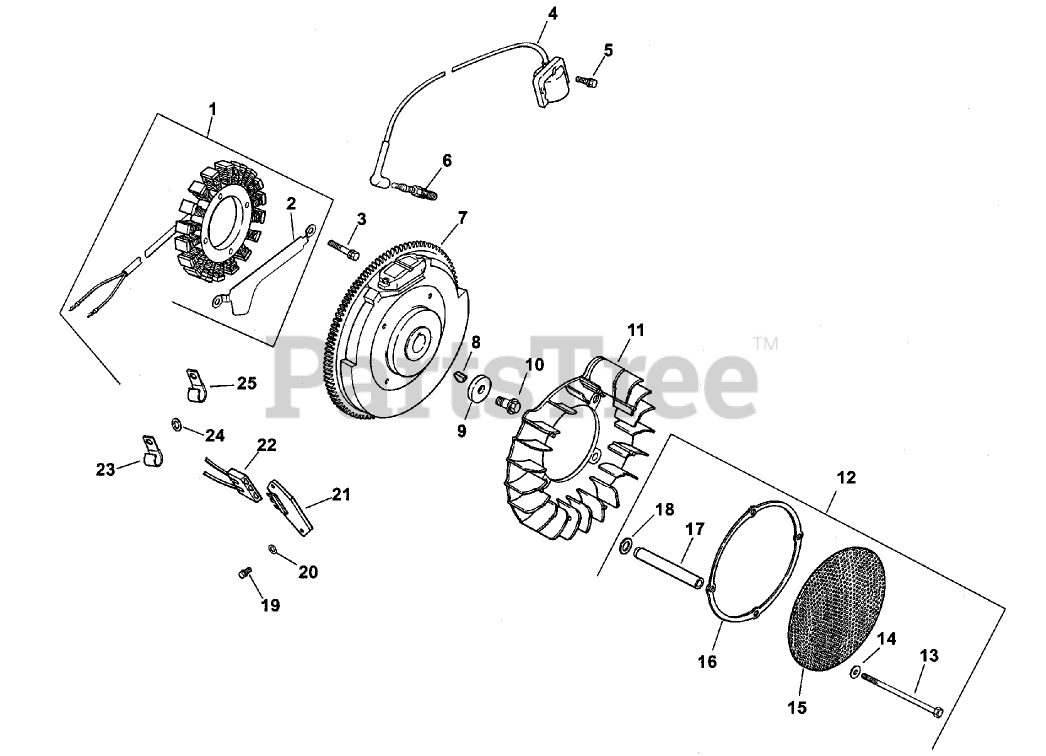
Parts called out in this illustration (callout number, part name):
1	Kit, 15 amp stator (Incl. 2)
2	Bracket-Wire, Stator
3	SCREW-THREAD FORMING (M5X0.8X25)
4	Module-Ignition
5	SCREW-FLANGE, THREAD FORMING (M5X.8X20)
6	Spark Plug
7	Flywheel
8	KEY (3/16 X 5/8)
9	WASHER-FLAT (13/32)
10	SCREW-FLANGE (M10X1.5X45)
11	Fan
12	Kit, chopper screen (incl. 13-18)
13	Screw-HH (M6x1.0x100)
14	WASHER-FLAT (1/4)
15	Screen-Grass
16	Ring-Support
17	Spacer
18	Washer-Spring (10MM)
19	SCREW-PHL HD (11-16X.88)
20	WASHER-FLAT (.188)
21	Rectifier-Regulator, 15 amp
22	Connector (3 contact)
23	CLIP-CABLE
24	WASHER-FLAT (1/4)
25	Clip-Cable
